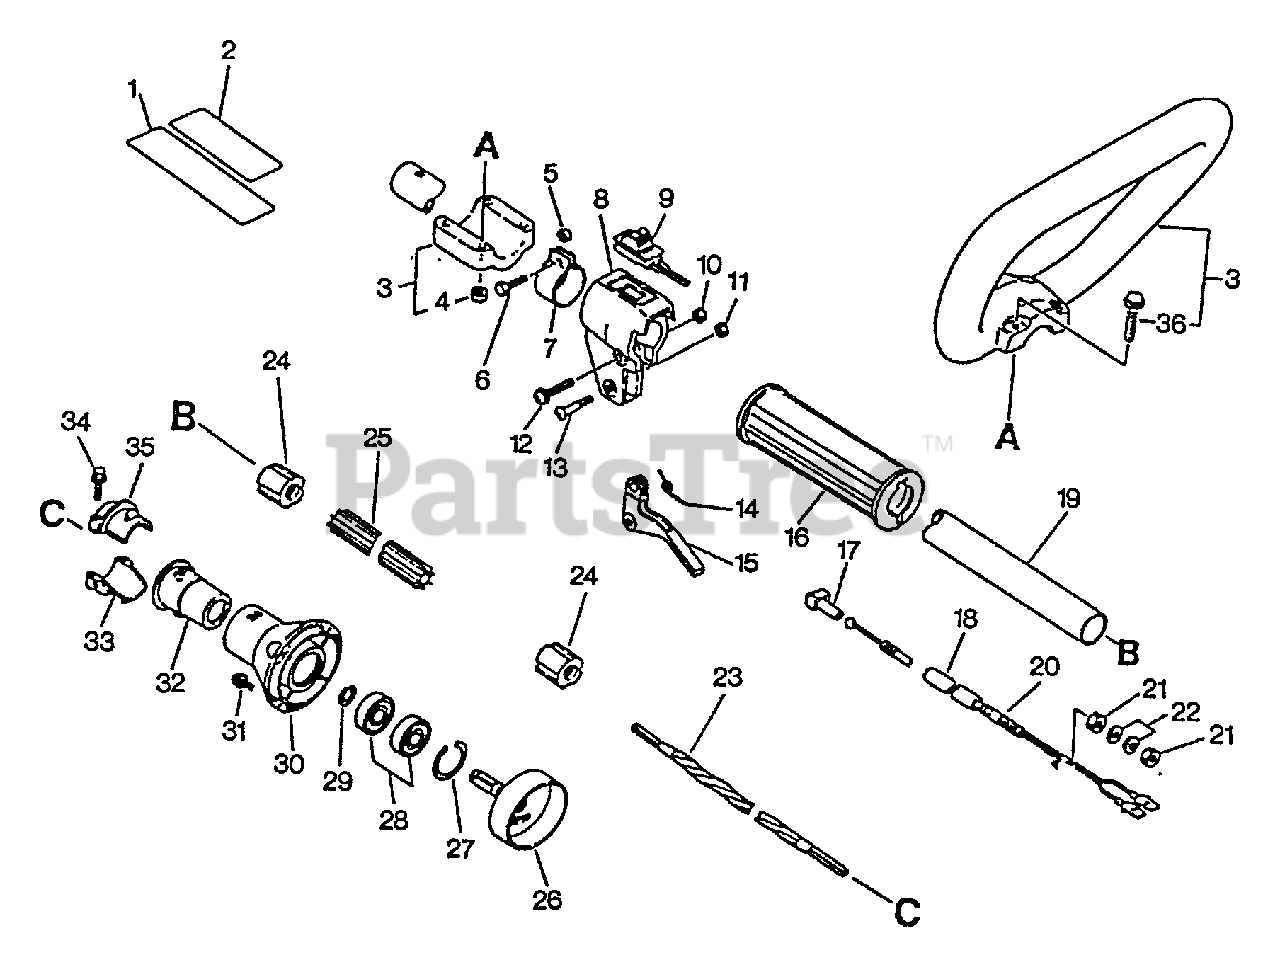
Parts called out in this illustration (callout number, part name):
1	LABEL - CAUTION
2	LABEL - CAUTION
3	LOOP HANDLE ASSY
6	BOLT - 5X18
8	BRACKET, THROTTLE CONTROL
9	IGNITION SWITCH ASSY
11	LOCKNUT - 5
12	SCREW - 5X30
13	SCREW - 5X30
14	SPRING, TRIGGER
15	TRIGGER, THROTTLE
16	GRIP, HANDLE
17	GUIDE, CABLE
18	TUBE - VINYL
19	MAIN PIPE ASSY
20	CABLE, THROTTLE
22	WASHER - 6
23	DRIVESHAFT - FLEXIBLE
25	LINER - FLEXIBLE
26	DRUM, CLUTCH
27	RING, RETAINING - 28
28	BEARING, BALL - 6001
29	RING, RETAINING - 12
30	CASE, CLUTCH - GRAY
31	SCREW - 5X16
33	CLAMP, MAIN PIPE
34	BOLT - 5X25
35	CLAMP, MAIN PIPE - UPPER
36	SCREW - 5X35
